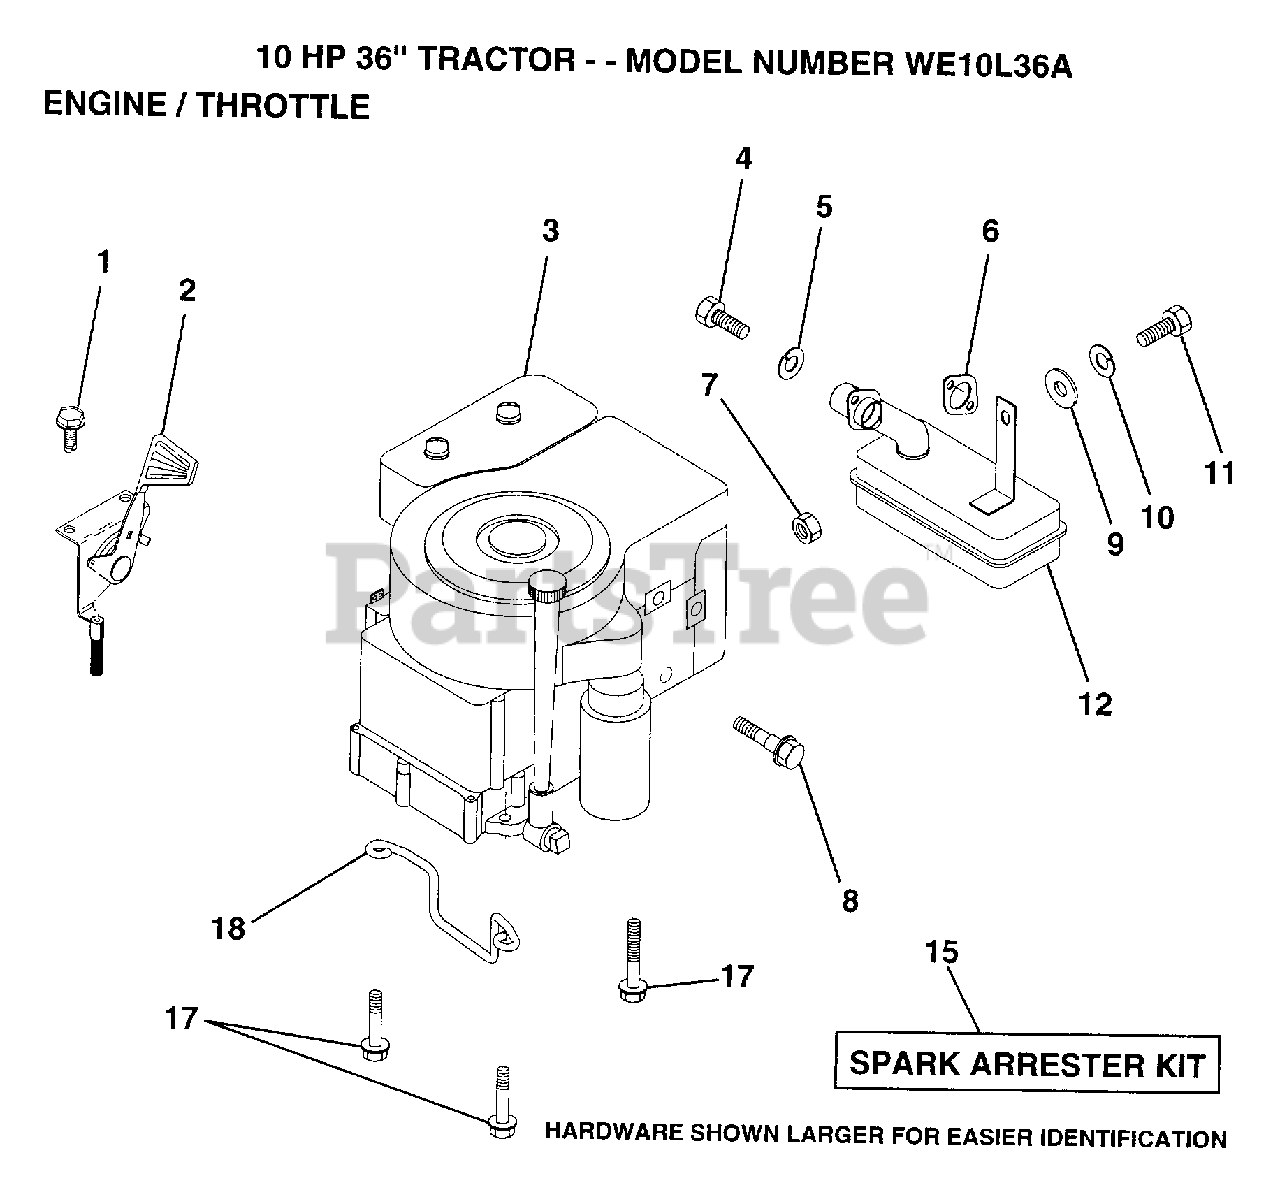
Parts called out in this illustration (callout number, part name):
1	SCREW.1/4-20X1/2
2	"CONTROL,THROTTLE"
3	ENGINE, B&S 10 HP
4	SCREW
5	LOCKWASHER
7	NUT.HEX.5/16-18
8	BOLT T
10	LOCKWASHER
11	BOLT
12	MUFFLER
17	SCREW LT
18	"KEEPER,DR BELT GR"
